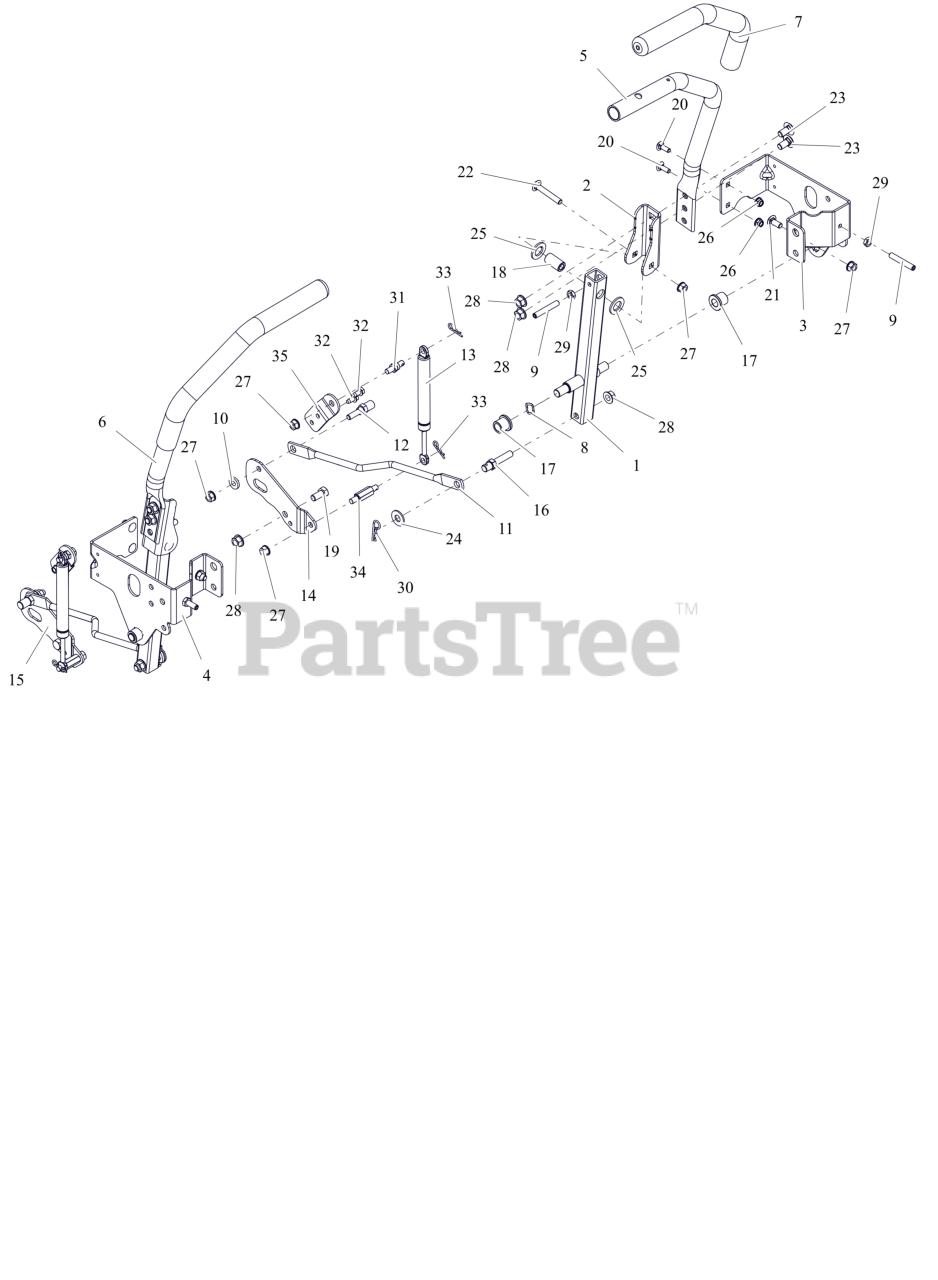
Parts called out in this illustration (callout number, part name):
1	WLDMT, LOWER CONTROL ARM (BLACK)
2	ARM, CONTROL -UPPER
3	BRKT, SPEED ADJ/SEAT PIVOT-LH (BLACK)
4	BRKT, SPEED ADJ/SEAT PIVOT-RH (BLACK)
5	WLDMT, CONTROL HANDLE -LH (BLACK)
6	WLDMT, CONTROL HANDLE - RH (BLACK)
7	GRIP, HANDLEBAR 15" FOAM
8	WAVE WASHER .531X.781X.125FH
9	SCR-SET, .312-18X2.000 SS
10	BSHG-FLG .316X.430X.225X.750
11	LINKAGE, STEERING
12	STUD, STEERING LINK-REAR
13	DAMPER, STRAIGHT MOUNT
14	PLATE, DAMPER RH
15	PLATE, DAMPER
16	STUD, STEERING LINK -FRONT
17	BHSG-FLG .500X.750X.750X.125
18	BSHG, -SLV .342 X .627 X 1.171
19	BLT,HEX .38-16X.75 G5 ZCC
20	BLT, RHSN .25-20X.750 G5 ZCC
21	BLT, RHSSN.31-18X.750 G5 ZCC
22	BLT, RHSSN .31-18X2.00 G5 ZCC
23	BTL,RHSSN .375-16 X 0.75 G5 FPB
24	WSHR,FLT .438X1.00X.083 ZCC
25	WSHR, FRICTION
26	NUT,NYL-FLG .25-20 GF ZCC
27	NUT,LK-CTR-FLG .31-18 GF ZCC
28	NUT-LK-CTR-FLG .375-16 GF ZCC
29	NUT-JAM .312-18 G2 ZCC
30	PIN, HAIR #203 .09X1.50 ZCC
31	COUPLER, DAMPER MOUNT
32	SCR-TAP .25-20X.50 HWH ZCC
33	PIN, HAIR #213 .08X1.19 ZCC
34	COUPLER, DAMPER MOUNT (LOWER)
35	PLATE, DAMPER TOP MOUNTING (BLACK)
